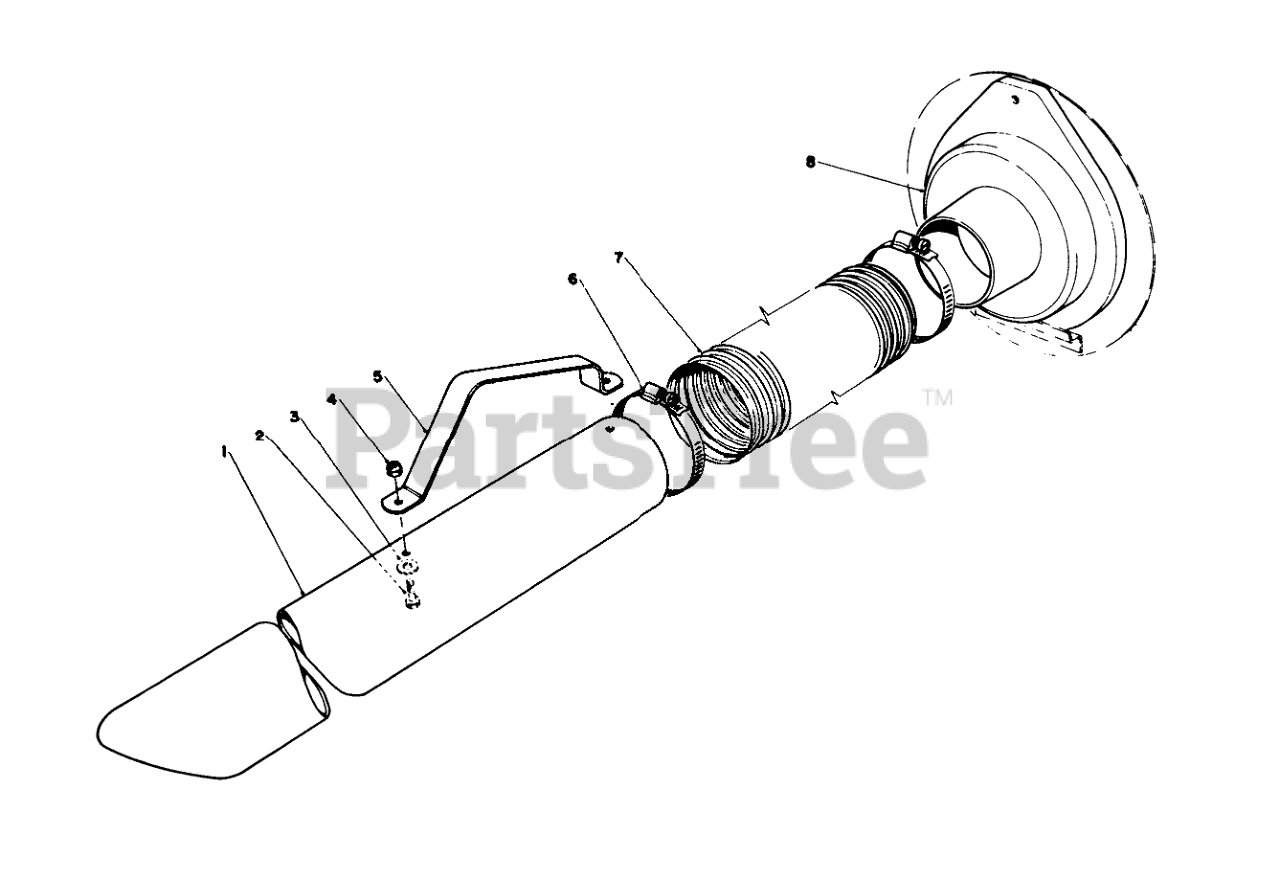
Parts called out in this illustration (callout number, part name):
1	NOZZLE
2	SCREW-HH
3	SPECIAL WASHER
4	NUT-KEPS
5	NOZZLE HANDLE
6	CLAMP
7	VACUUM HOSE
8	ADAPTOR HOSE TO HSG
